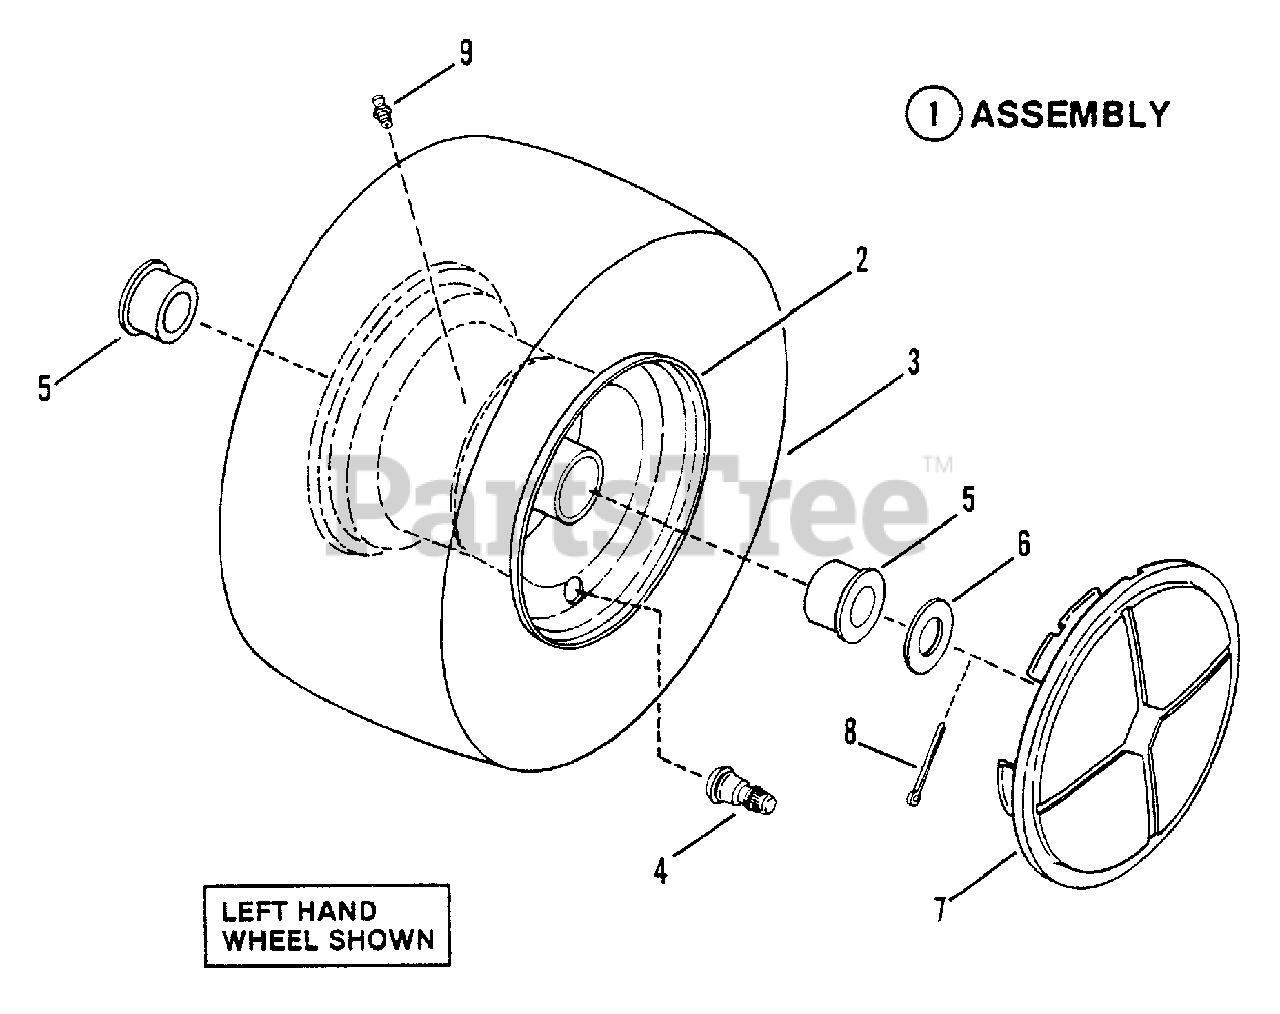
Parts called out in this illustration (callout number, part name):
1	ASSEMBLY, Front Tire & Rim
2	RIM, 6 x 4.50
3	TIRE, 15-6.00 x 6
4	VALVE, Air (Snap-In)
5	BEARING, Wheel
6	WASHER, 49/64 x 1-1/2" O.D. Flat
7	COVER, Wheel
8	PIN, 5/32 x 1" Cotter
9	FITTING, Lube 1/4-28 Tapered Thread
